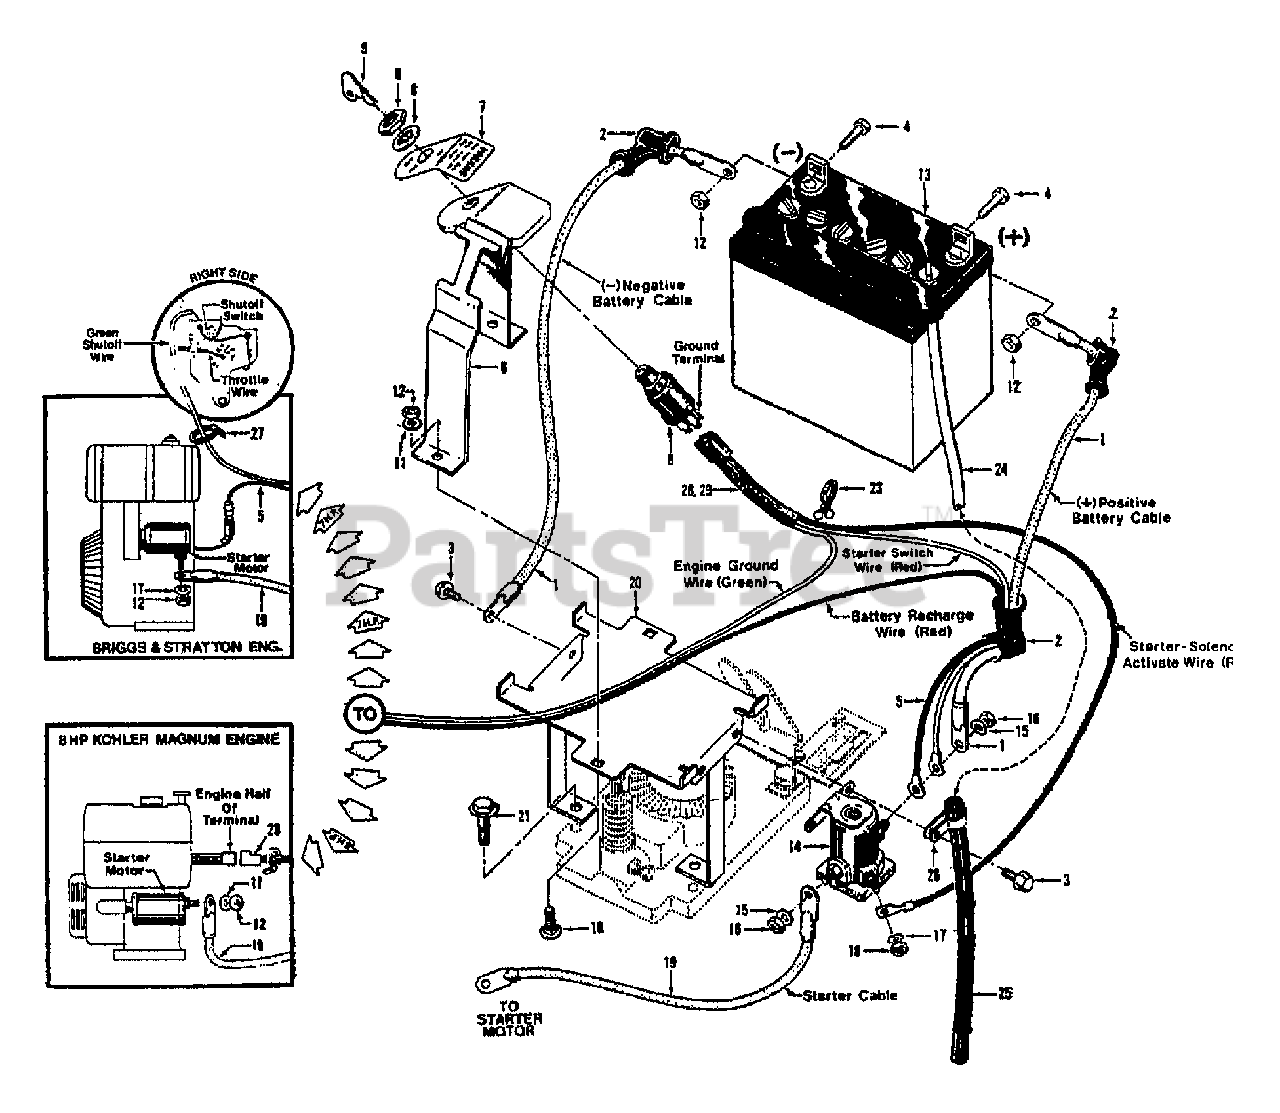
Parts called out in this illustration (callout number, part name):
1	CABLE-BATTERY 10"
2	BOOT-BATTERY CABLE
3	SCR-HWH 1/4-20 X .5 STH
4	SCR-HH 1/4-20X.625
5	WIRE-RECHARGE 5&7 BRIGGS
6	CLAMP-KEYSWITCH W/DECAL OPC (INCL. #97127)
7	DECAL-KEYSWITCH
8	KEYSWITCH W/KEYS (INC. (2) 9, 1 LOCKWASHER & 1 MOUNTING NUT. N/A SEPARATELY)
9	KEYS(1 PAIR) FOR SWITCH
10	SCR-CARR 1/4-20X1.25
11	WASHER-LK .25 ZP
12	NUT-HEX 1/4-20 ZP
13	BATTERY-12 VOLT HORSE
14	KIT-SOL W/HDW
15	WASHER-LK .312 ZP
16	NUT-HEX 5/16-24
17	WASHER-EXTERNAL TOOTH 1
18	NUT-HH M10-32X.125
19	CABLE-BATTERY 12"
20	BRKT-BATTERY OPC PNT
21	SCR-HFLK 3/8-16X1.50
23	TIE-TWIST LOCK
24	TUBE-VENT BATTERY/HSE
25	TUBING-RUBBER
26	CLAMP
27	TIE-RED
28	ASSM-HARNESS 2647/20857
29	HARNESS-WIRE 3.5
